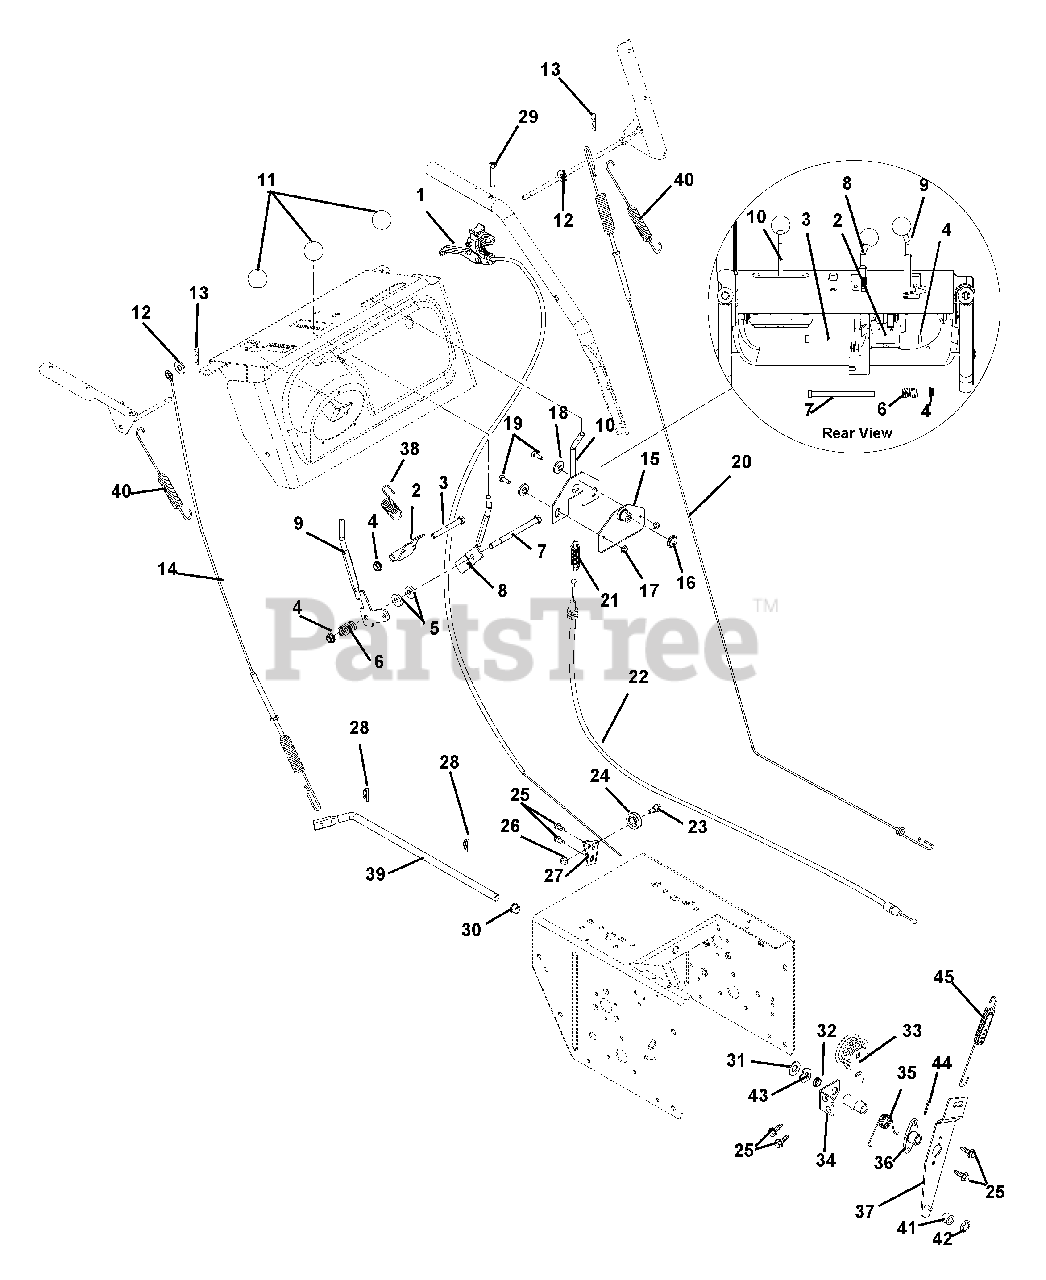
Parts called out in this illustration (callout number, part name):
1	CABLE, TRIGGER-DIFFERENTIAL
1	CABLE, TRIGGER-REMOTE WHEEL
2	ARM, INTERLOCK
3	@BLT-HEX .38-16X3.00 GR5 YWZC
4	@NUT-LK-TOP-FLG .38-16 YWZC
5	WSHR-FL-STL .406X1.00X.188 YWZ
6	SG-COMP .125X.781X1.250
7	@BLT-HEX .38-16X5.00 GR5 YWZC
8	CONTROL, DEFLECTOR
9	LEVER, SHIFT
10	LEVER, CHUTE CONTROL
11	KNOB,BALL -BLACK 1.47" .375-16
12	@WSHR-FL-STL.281X.62X.065 YWZC
13	PIN-HAIR INT .06X.18X.77
14	CABLE, ATTACHMENT
15	MOUNT, CHUTE CONTROL
16	BUSHING, POLYLINER-.75 SNAPIN
17	@NUT-LK-TOP-FLG .25-20 YWZC
18	BSHG-FLG .265X.448X.243X1.00
19	@BLT-HEX .25-20X.75 GR5 YWZC
20	CABLE, TRACTION
21	SG-TENS .048X.44X1.75 WLD 9
22	CABLE, CHUTE LOCK
23	BOLT, SHLDR-.375X.375X.25-20
24	PULLEY, CABLE
25	@SCR-TAP .25-20X.50 HWH TR YWZ
26	@NUT-LK-TOP-FLG .25-20 YWZC
27	BRACKET, CABLE PULLEY
28	CLIP, SPRING
29	SCR-MCH .25-20X1.50 OVAL HD
30	BUSHING, POLYLINER-.50 SPLIT
31	@WSHR-FL-STL.531X1.06X.095YWZC
32	BUSHING, POLYLINER-.50 SNAPIN
33	ARM, IDLER-TRACTION
34	BRACKET, SUPPORT
35	SG-TORS .067X.88
36	HUB, BRAKE ARM
37	ARM, IDLER-ATTACHMENT
38	SPRING-EXT .047X.438X1.45
39	ARM, ATTACHMENT
40	SG-TENS .056X.60X4.40
41	BSHG,SLV .265 X .625 X .375
42	RG-RTNG-EXT .250X.010
43	WAVE WASHER .531X.781X.125FH
44	PIN-ROLL .125X1.00
45	SG-TENS .06X.482X5.35
